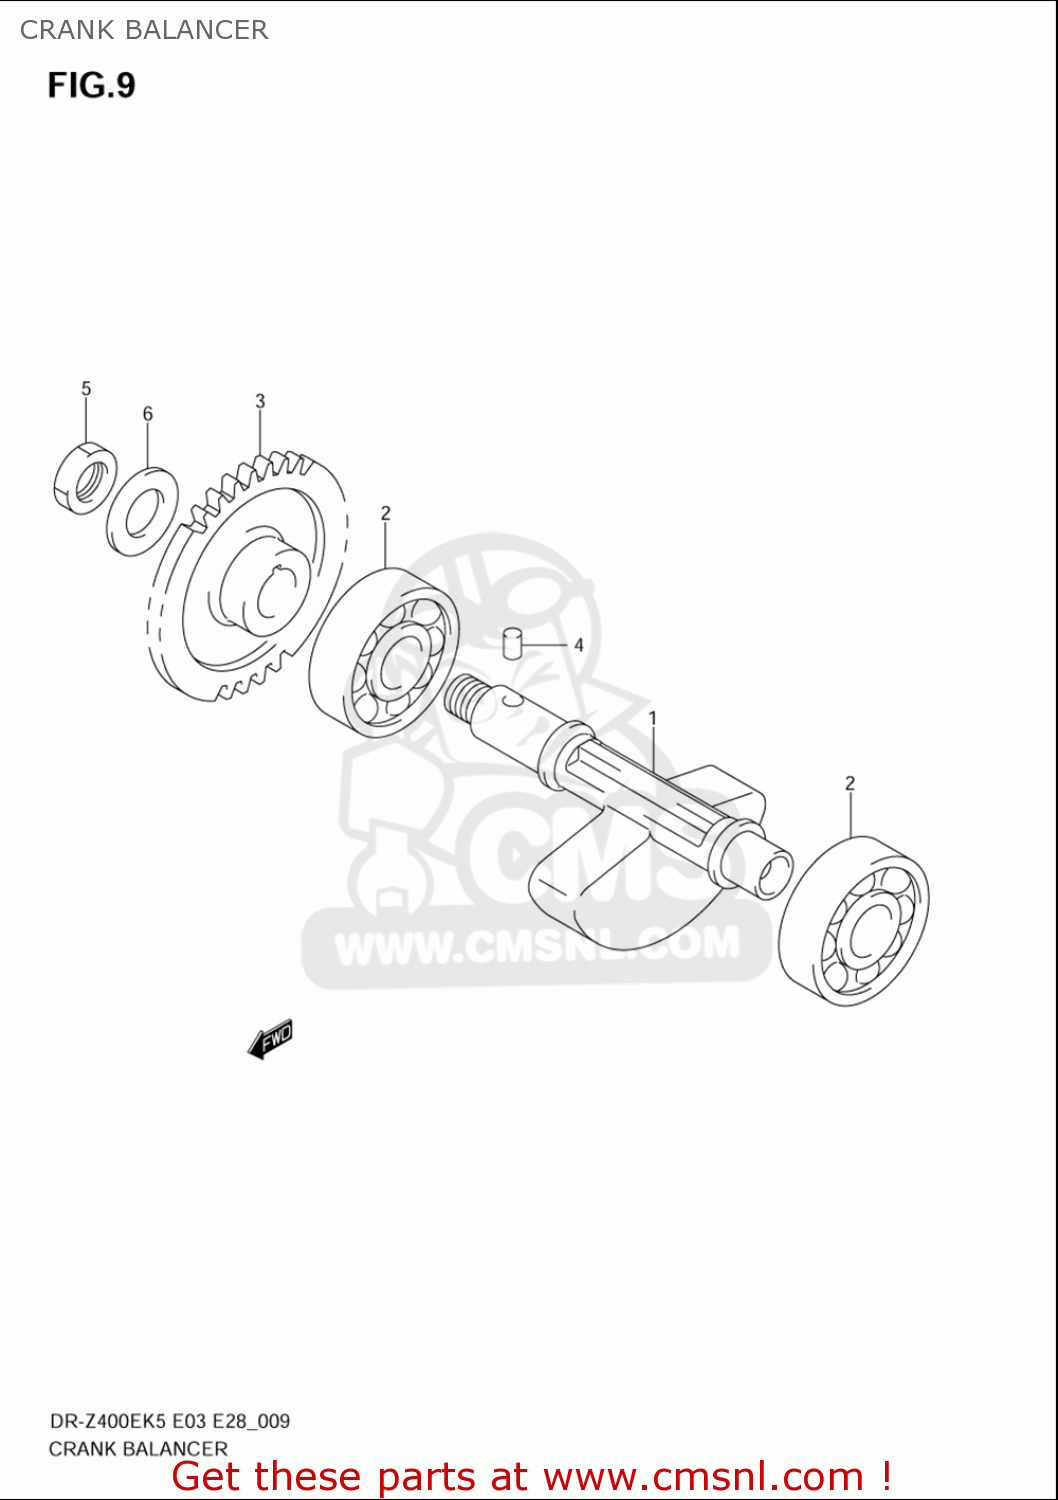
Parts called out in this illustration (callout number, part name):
1	BALANCER,CRANK
2	BEARING(15X42X13)
3	GEAR,CRANK BALANCER DRIVEN
4	PIN(5X8)
5	NUT
6	WASHER(12.5X26X1.6)
